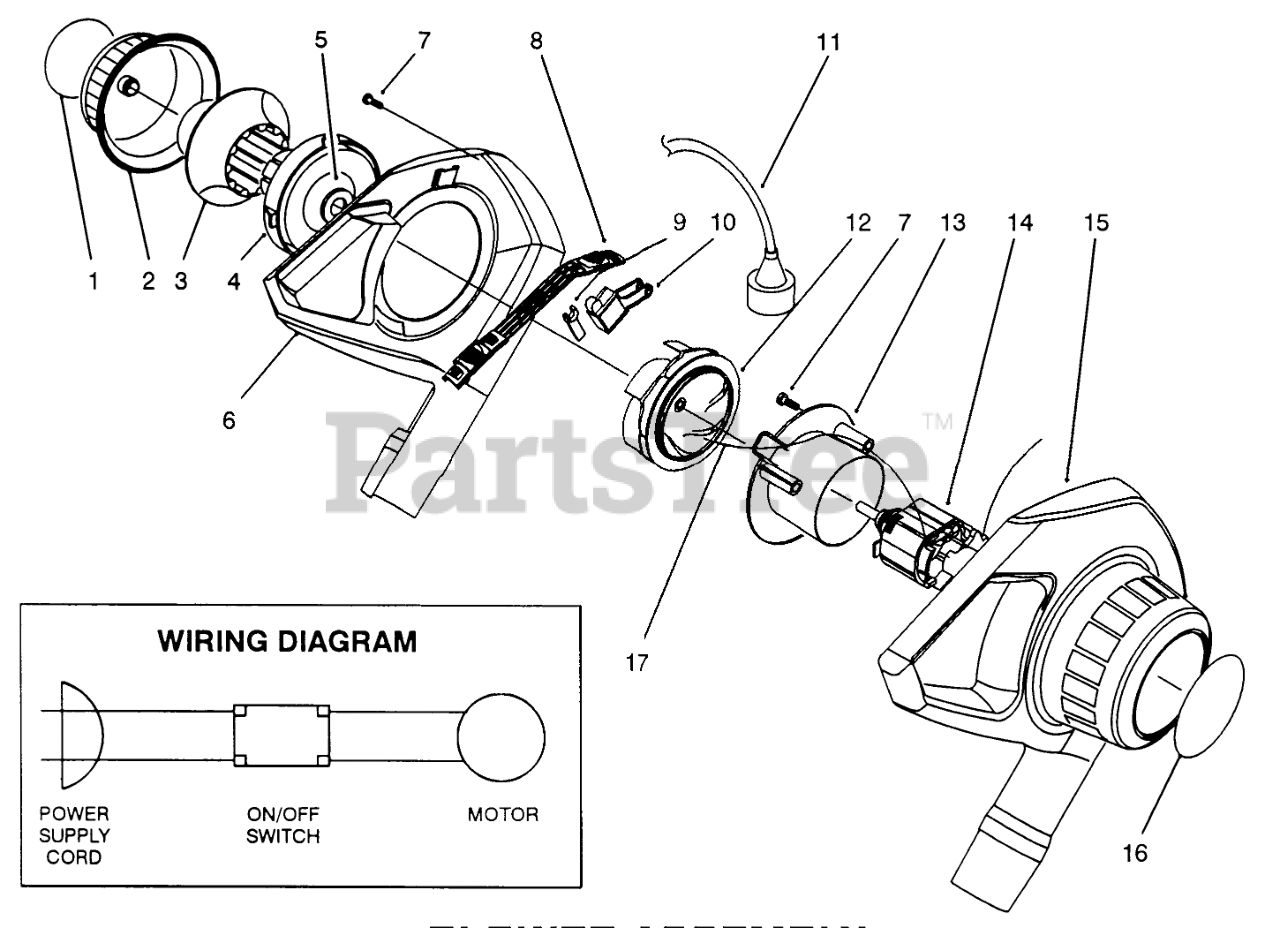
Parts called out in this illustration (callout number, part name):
1	DECAL, 700 CHOKE
2	CHOKE COVER, 600/700
3	MID BL-RING CHOKE
4	MID-BLOWER BASE CHOKE
5	RETAINER CLIP
6	HOUSING ASSY, RH
7	Screw
8	SWITCH BAR, 600/700
9	MID BL-ACTUATOR
10	SWITCH
11	POWER SUPPLY CORD
12	Impeller Assembly
13	RETAINING PLATE
14	Motor
15	HOUSING, LH
16	SERIAL DECAL 700
